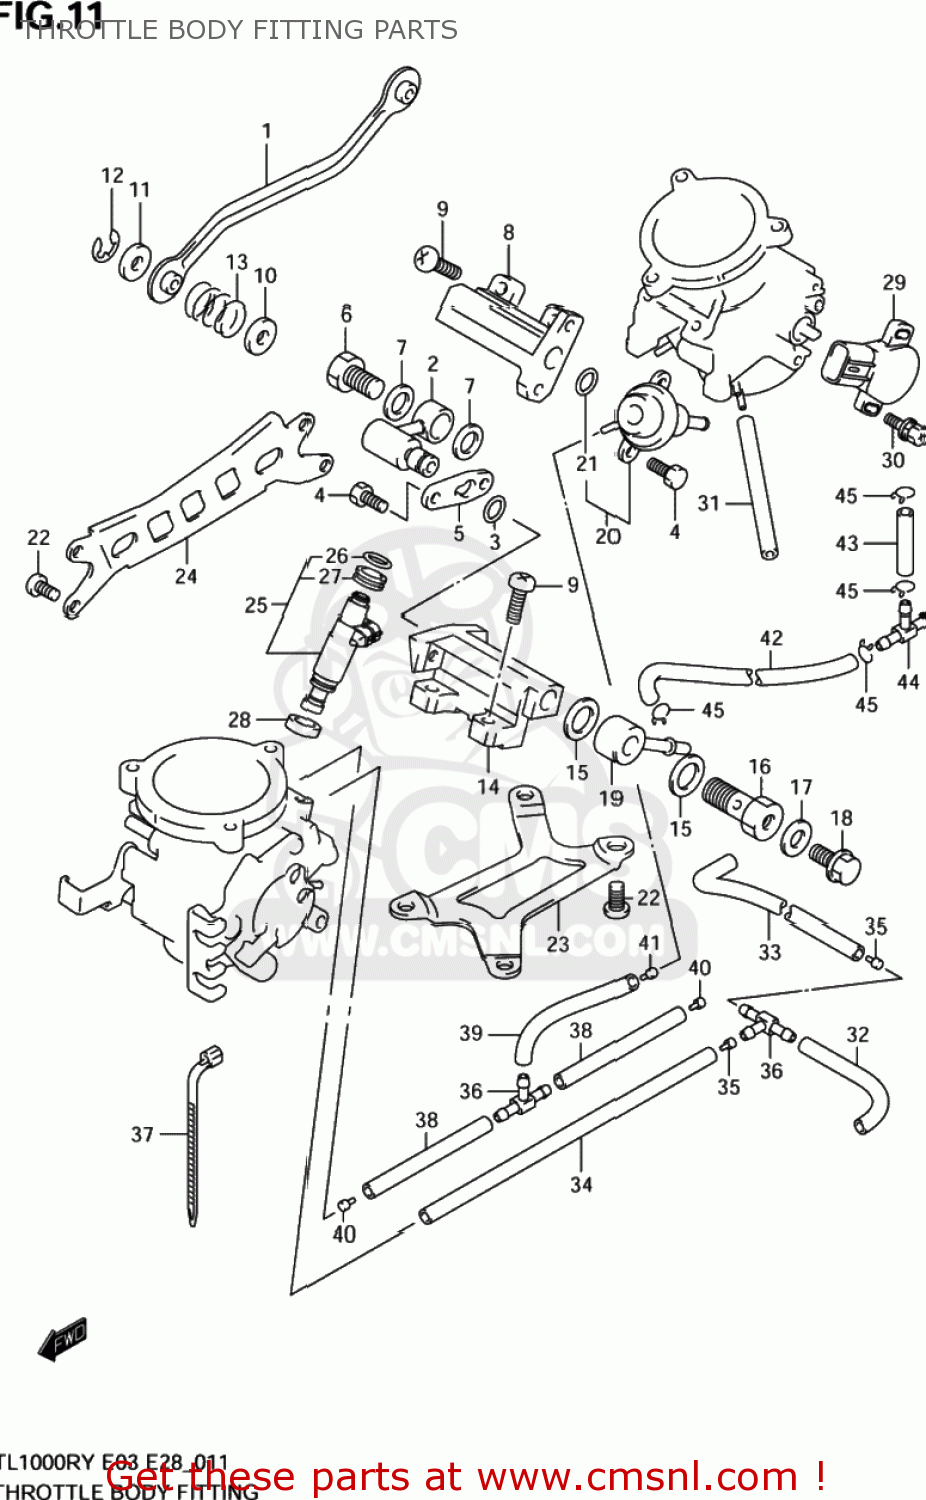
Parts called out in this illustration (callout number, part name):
1	LEVER ASSY
2	PIPE ASSY
3	O-RING
4	BOLT
5	PLATE
6	BOLT
7	WASHER
8	PIPE,DELIVERY
9	SCREW
10	RING
11	RING
12	E RING,ACCELETION LEVER
13	SPRING
14	PIPE,DELIVERY
15	GASKET,UNION BOLT (NAS)
16	BOLT,UNION FUEL FILTER
17	GASKET(5.8X13X1.2) (NAS)
18	UNION BOLT,AIR VENT
19	UNION,FUEL HOSE
20	REGULATOR,FUEL
21	O RING
22	SCREW
23	PLATE
24	PLATE
25	INJECTOR ASSY,FUEL
26	O RING
27	GROMMET
28	CUSHION,FUEL INJECTOR
29	SENSOR ASSY,THROTTLE
30	SCREW
31	HOSE(3.5X7.5X600)
32	HOSE(3X7X600)
33	HOSE
34	HOSE
35	JET,AIR(180)
36	3WAY,VACUUM HOSE
37	CLIP
38	HOSE(3X7X600)
39	HOSE(3X7X600)
40	JET
41	JET
42	HOSE
43	HOSE
44	NIPPLE
45	CLIP
